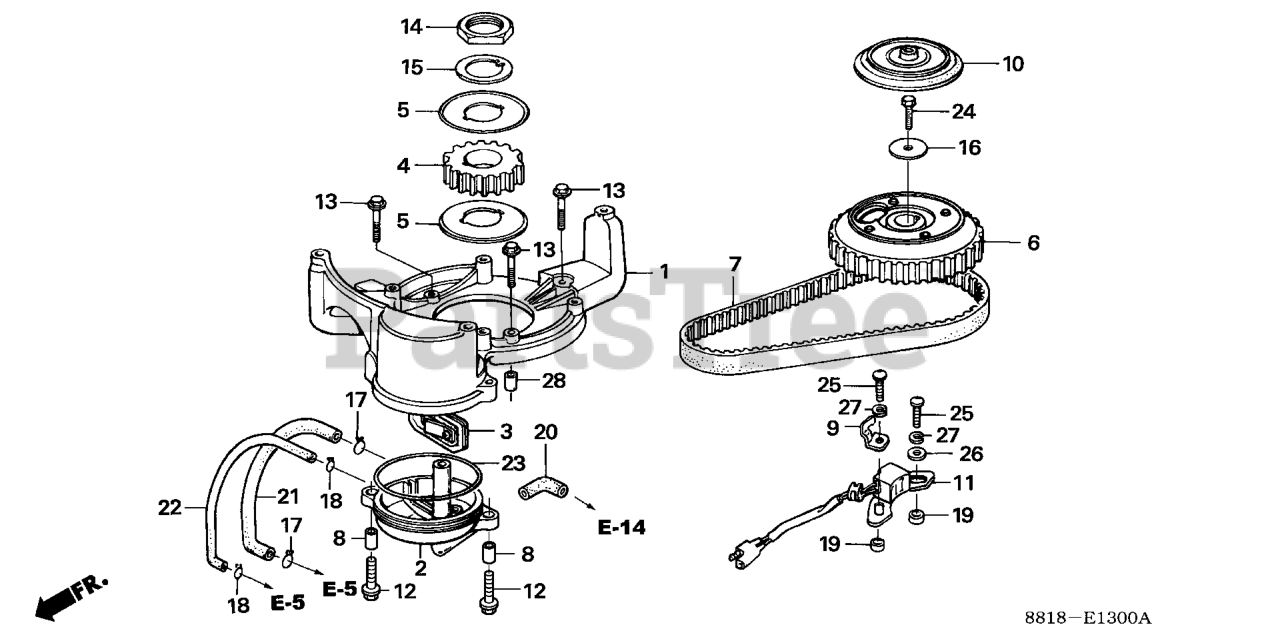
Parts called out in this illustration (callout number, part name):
1	CASE, STARTER *NH8* (DARK GRAY)
2	COVER, BREATHER
3	BODY, VALVE
4	PULLEY, TIMING
5	FLANGE, TIMING PULLEY
6	PULLEY, CAMSHAFT
7	BELT, TIMING
8	COLLAR A, DISTANCE
9	PLATE, WIRE CLAMP
10	COVER, POINT
11	COIL ASSY., PULSER
12	BOLT, FLANGE (6X22)
13	BOLT, FLANGE (6X28)
14	NUT, LOCK (24MM)
15	WASHER, LOCK (24MM)
16	WASHER, WHEEL (6MM)
17	CLIP, TUBE (B12)
18	CLIP B7, TUBE
19	PIN, DOWEL (7X4.5)
20	TUBE B, BREATHER
21	TUBE C, BREATHER
22	TUBE, OIL RETURN
23	O-RING (62X2.5)
24	BOLT, HEX. (6X22)
25	SCREW, PAN (5X14)
26	WASHER, PLAIN (5MM)
27	WASHER, SPRING (5MM)
28	PIN A, DOWEL (8X10)
